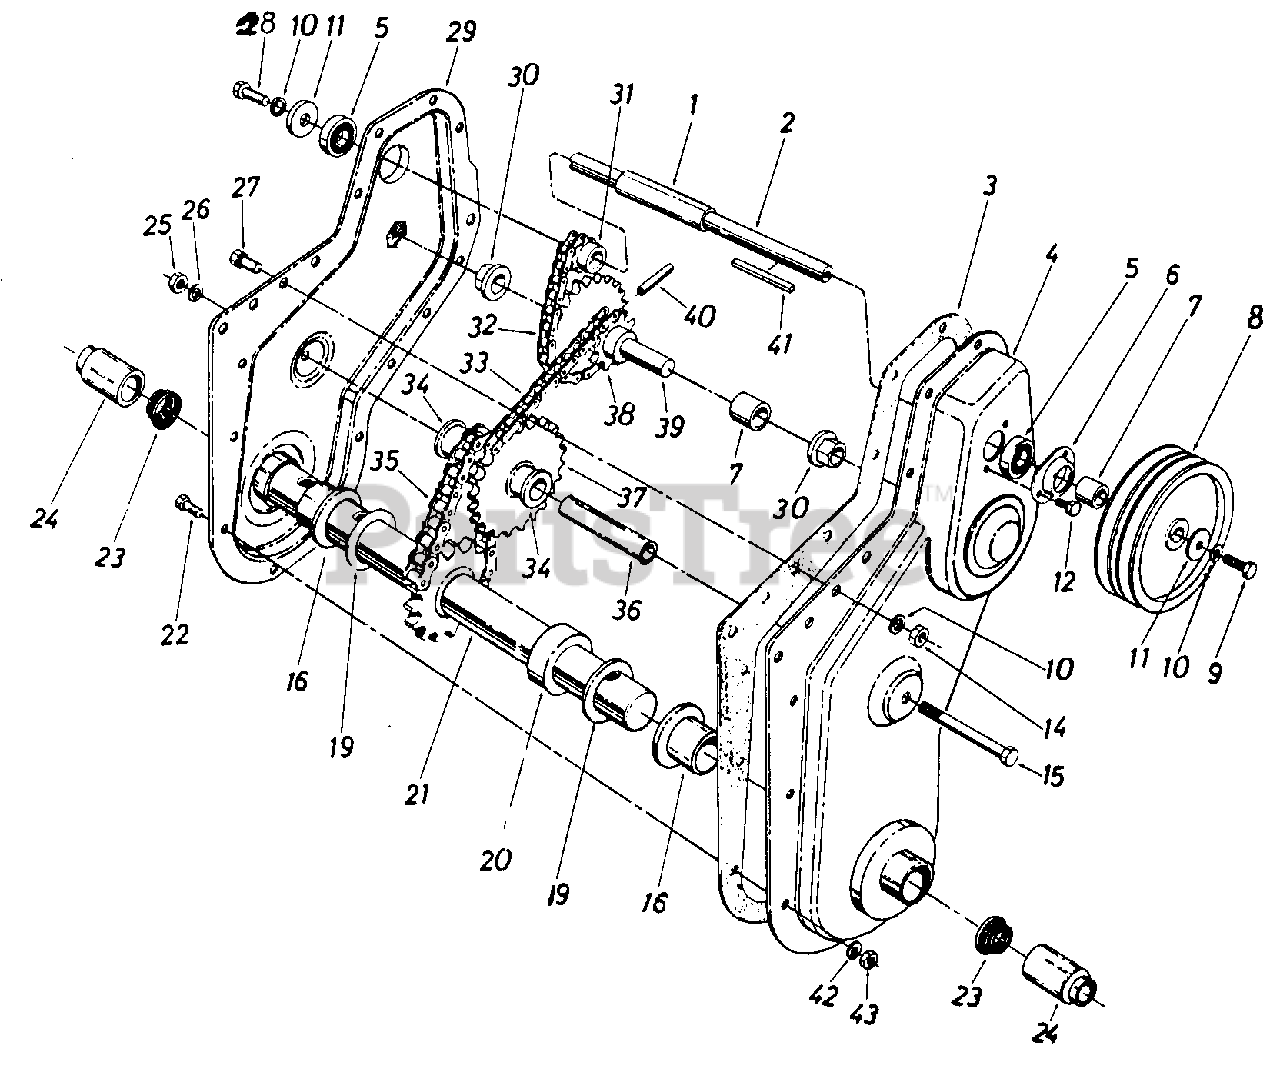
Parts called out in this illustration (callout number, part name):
2	SHAFT-JACK
3	GASKET
4	CHAIN CASE HALF-LH
5	BEARING-BALL
6	HOUSING-BRG
7	SPACER-.635 ID X .88 OD X 1.03
9	SCREW-HEX 5/16-18 X 10 SPEC
10	WASHER-LOCK-5/16
11	WASHER-FL-.312 X 1.125 X .125
12	SCREW-HEX WASH SF TAPP
14	NUT-HEX 5/16-18
15	SCREW-HEX 3/8-16 X 3.25
16	BEARING-KING PIN
19	WASHER-FL-1.03 ID X 1.62 X .03 HD
21	SHAFT-TINE
22	SCREW-HEX 1/4-28 X .62
24	CAP-DUST
25	NUT-HEX 3/8-16
26	WASHER-LOCK-3/8
27	SCREW-HEX SEMS 5/16-18 X 1.00
28	SCREW-HEX 5/16-18 X .62
29	CHAIN CASE HALF-RH
30	BEARING-HEX FLANGE
31	SPROCKET ASSY-10T
32	#41 CHAIN 1/2 PITCH X 34 LINKS E
33	#420 CHAIN 1/2 PITCH X 48 LINKS
34	BEARING-FLANGE .626 ID
35	#50 CHAIN 5/8 PITCH X 28 LINKS
36	SHAFT-SPROCKET
37	SLEEVE ASSY-SPRKT
38	SLEEVE ASSY-SPRKT
39	SHAFT-SPROCKET
40	PIN-SPRING SPIRAL 1/4X1.5 HEAVY DT
41	KEY-SQ 3/16X1.50
42	LOCK WASHER 1/4 DIA
43	NUT-HEX 1/4-28
